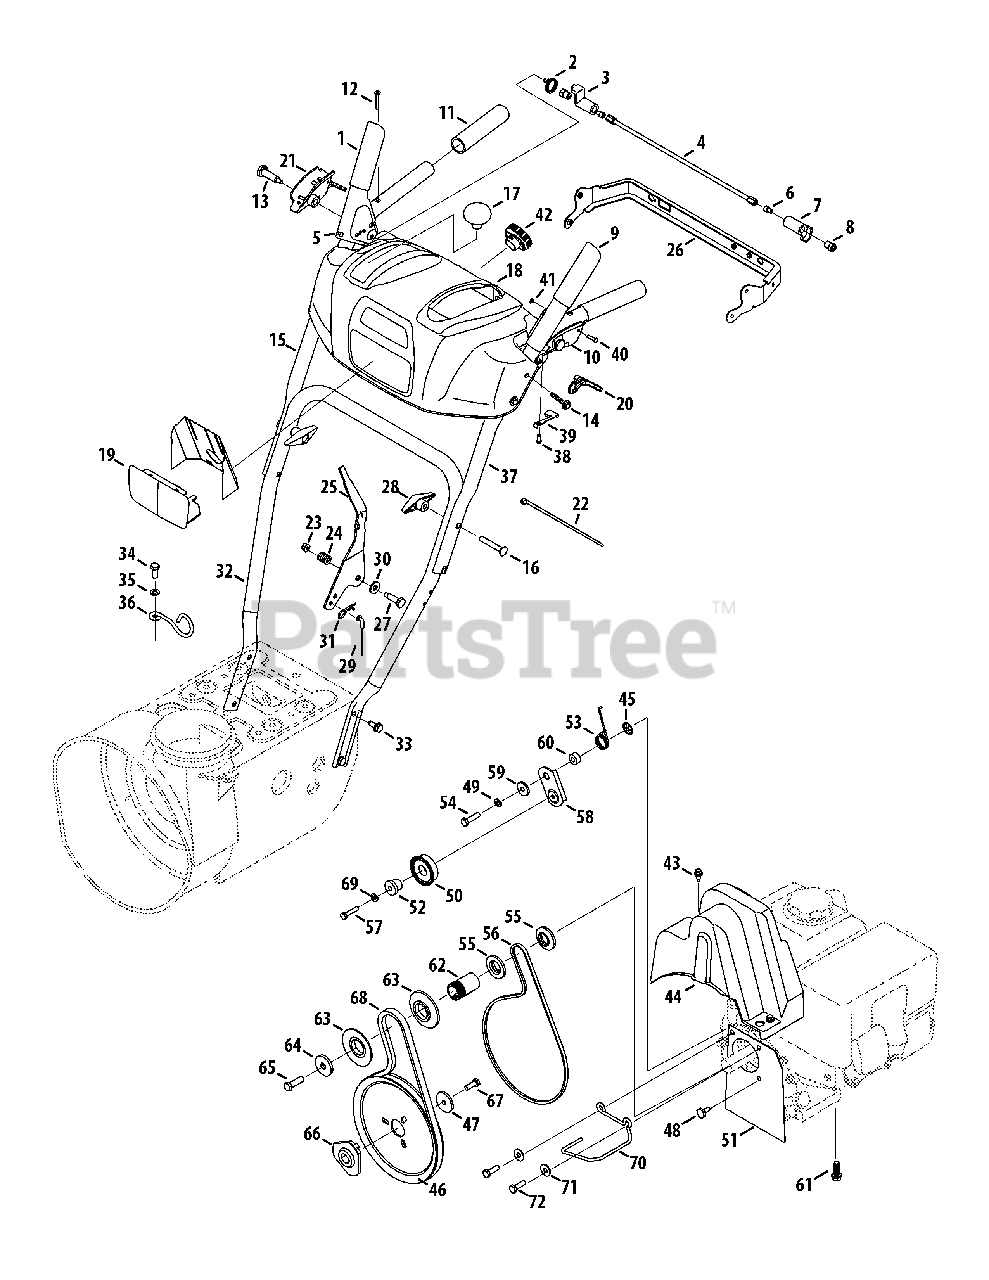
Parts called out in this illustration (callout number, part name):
1	Handle Engagement Ass’y RH
2	Torsion Spring
3	Lock Plate
4	Pivot Rod
5	Rubber Bumper
6	Screw, 1/4-20 x .500
7	Clutch Lock Cam
8	Shoulder Nut, 1/4-20
9	Handle Engagement Assembly LH
10	Handle Clutch Lock LH Assembly
11	Handle Grip
12	Screw, #10-24 x 0.375
13	Shoulder Screw, 1/4-20
14	Screw, 1/4-20 x 1.625
15	Upper Handle RH
16	Carriage Screw, 5/16-18 x 2.25
17	Shift Knob
18	Handle Panel
20	Steering Control
21	Handle Clutch Lock RH Assembly
22	Cable Tie
23	Flange Lock Nut, 1/4-20
24	Compression Spring
25	Shift Lever
26	Panel Bracket
27	Shoulder Screw
28	Wing Knob
29	Speed Selector Cable
30	Flat Washer
31	Click Pin
32	Lower Handle
33	Screw, 5/16-18 x 0.75
34	Screw, M8-1.25
35	Flat Washer, .330 x .630 x .0635
36	Cable Control Wire
37	Upper Handle LH
38	Screw, #8-16 x 0.50
39	Clutch Lock Spring
40	Pin, 3/16
41	Retainer Ring
42	Headlight Socket
43	AB Screw, 1/4-20 x 0.625
44	Belt Cover
45	Push-on Nut
46	Auger Pulley
47	Flat Washer
48	Shoulder Screw
49	Lock Washer
50	Idler Pulley Assembly
51	Plt., Cvr.
52	Spacer
53	Torsion Spring
54	Hex Screw, 5/16-24 x 1.25
55	Pulley Half
56	Belt, Wheel Drive
57	TT Screw, 1/4-20 x 1.25
58	Drive Clutch Idler Bracket
59	Shoulder Spacer
61	TT Sems Screw, 3/8-16 x 1.0
62	Spacer
63	Pulley Half
64	Flat Washer
65	Hex Bolt, 3/8-24 x 1.25
66	Pulley Adapter
67	Hex Bolt, 5/16-24 x 0.875
68	V-Belt,.500 x 35.00 Lg
69	Lock Washer
70	Belt Guide
71	Flat Washer, .349 x .879 x .063
72	Screw, 5/16-24 x 1.00
